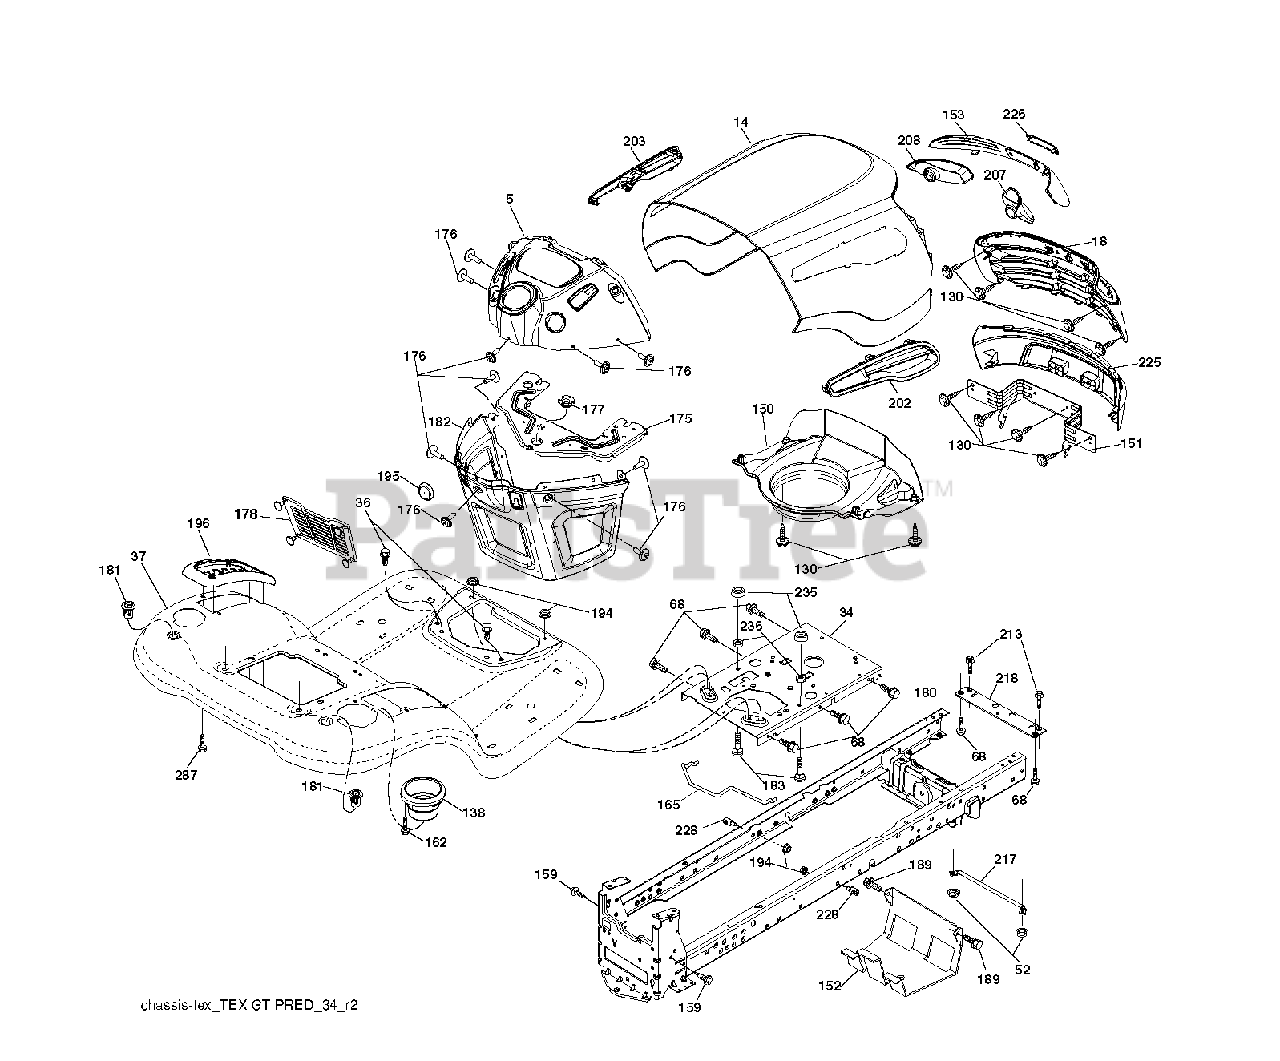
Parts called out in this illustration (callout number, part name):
34	PLATE.ENGINE.WELDED.CHASSIS
36	SCREW 5/16"
52	LOCKNUT
130	SCREW.#10 X 0.750.BOS THREAD
138	CUPHOLDER.TL.TEX.BLACK
152	SHIELD BROWNING
159	SCREW, 3/8-16X3/4
162	SCREW.HI-LO.CONSOLE
175	PLATE.CROSSMEMBER.HUSQ
176	SCREW.#10-24X5/8.RN.QU
177	BUSHING,STEERING
178	CARGO.ASM.NET.TXGT.W/C
180	CHASSIS
181	FEND/FTRST.PCH.CPH.NFW
182	DASH.LOWER.COMMON.12V.ADAPTOR
183	BOLT.5/16-18X1-1/4 FULL.THREAD
189	SCREW
194	NUT LOCK HEX FLANGE 5/16-18
195	PLUG.HOLE.DASH.LOWER.12V.BLK
196	CONSOLE.ASM.DECKLFT.BL/RBT.TLT
213	BOLT
217	ROD.PIVOT.HOOD
218	X-PIECE.HOOD.STOP.NON/
228	STUD.FASTNER.W/ANTI-ROTATE
235	SPACER FENDER
236	NUT.CENTERLOCK.5/16-
